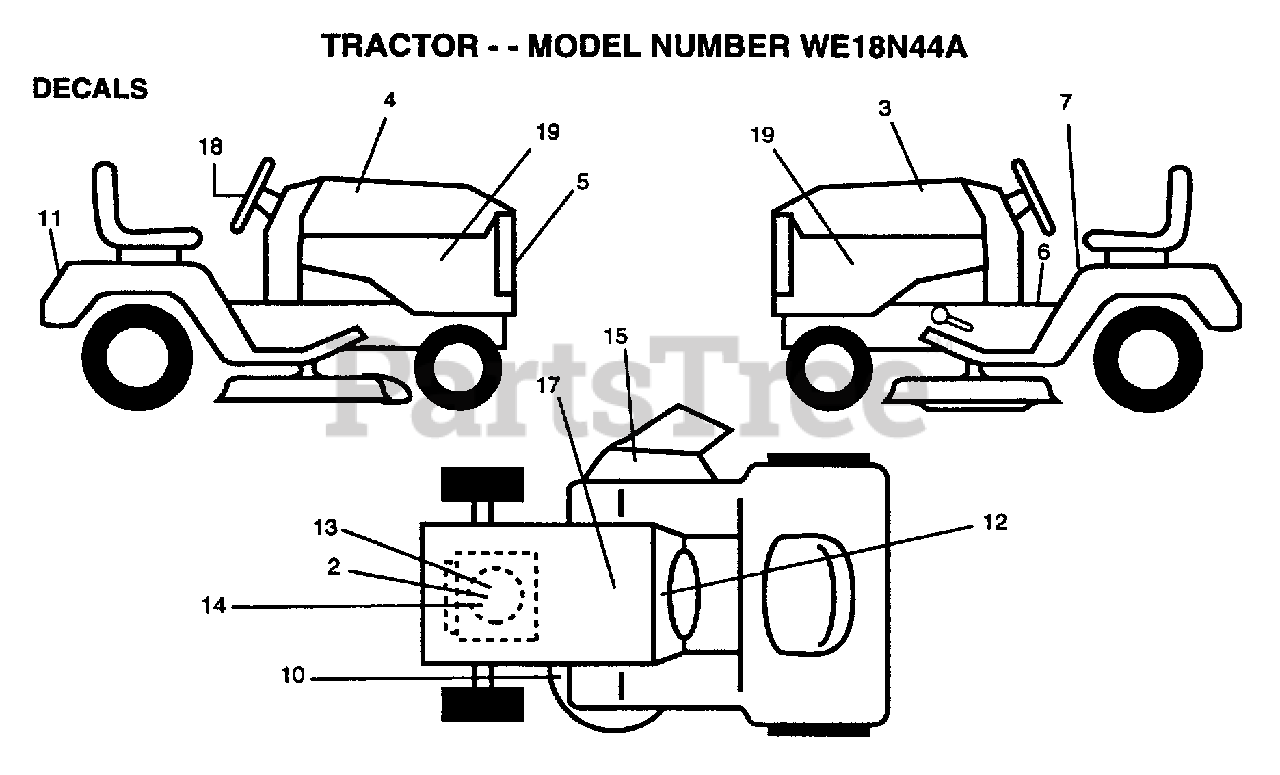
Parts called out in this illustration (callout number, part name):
2	DECAL.ENG.272757
3	DECAL.HD.LH.YT/GT
4	DECAL.HD.RH.YT/GT
5	DECAL.GRILL
6	DECAL BRAK PARK
7	DECAL CAUTION
10	"DECAL.V.BELT.44"""
11	DECAL.FENDER
12	DECAL.DASH.INSTR.
13	DECAL.ENG.272101
15	"DECAL, WARNING"
17	DECAL
18	DECAL.WHL.STRG.
19	DECAL.PNL.SD.18HP
